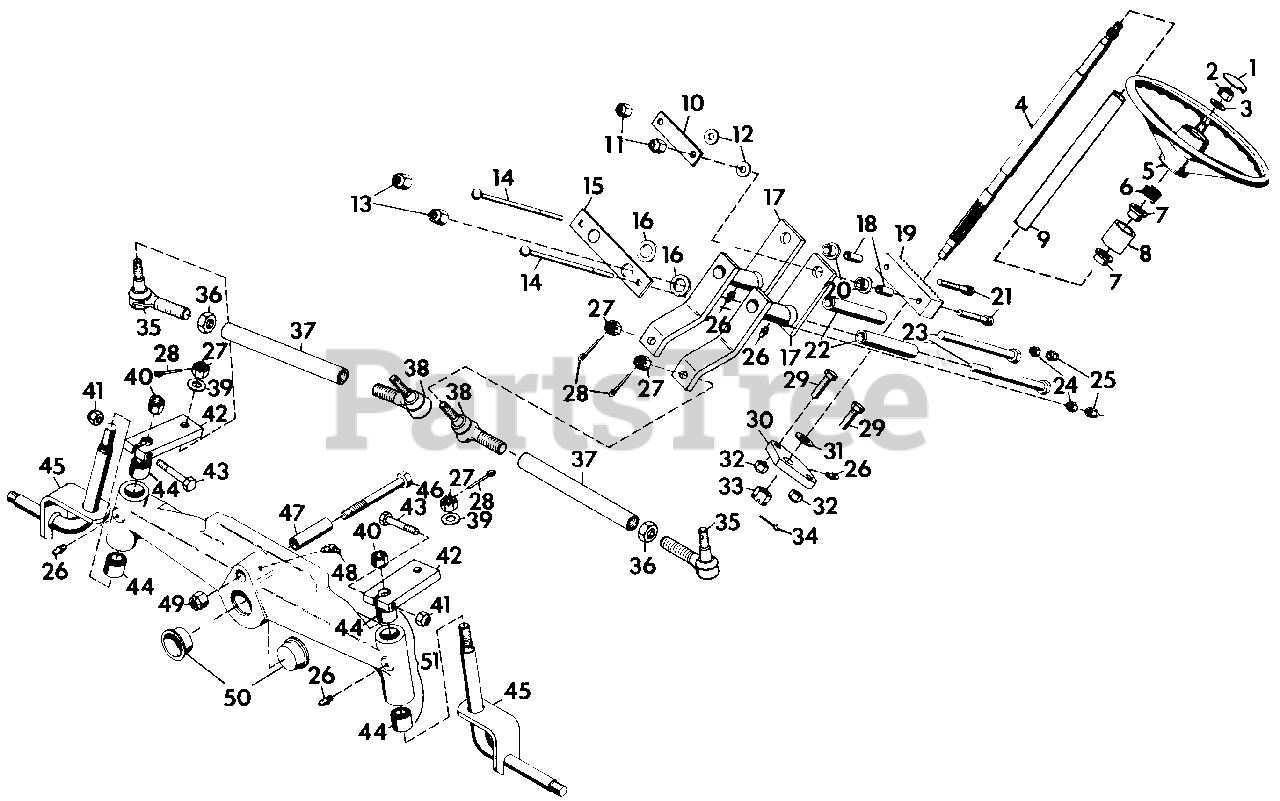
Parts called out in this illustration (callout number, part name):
1	CAP, STEERING WHEEL
2	NUT, JAM 5/8-11 HEX
3	WASHER, FLAT .656X1.312X.095
4	SHAFT, STEERING WHEEL
5	WHEEL, STEERING
6	SPRING, COMP. 1.00X.80X36 LB/IN
7	BUSHING, NYLON .760X1.000X.600 FLANGE
8	BUSHING, STEERING WHEEL
9	TUBE, PLASTIC 1.0 I.D.
10	STRAP, RACK AND PINION
11	NUT, LOCK 3/8-16
12	WASHER, FLAT .375X1.125X.065
13	NUT, LOCK 1/2-13
14	BOLT, 5/16-18X5.5 RD HD SQ NK
15	PLATE, ADJUSTMENT
16	RACE, BEARING THRUST .752X1.240X.095
17	WELDMENT, STEERING
18	BUSHING, .391X.622X.670
19	GEAR, RACK
20	BEARING, FLANGE(P/M BRONZE)
21	SCREW, CAP 3/8-16X2.0 HEX SOCKET HD
22	SLEEVE, PIVOT
23	BOLT, HEX 1/2-13X6.0
24	NUT, HEX 5/16-18
25	NUT, LOCK 5/16-18
26	FITTING, LUBE 1/4-28
27	NUT, HEX SLOTTED 3/8-24
28	PIN, COTTER .09X.75
29	BOLT, HEX 7/16-14X1.5
30	SUPPORT, STEERING SHAFT
31	RACE, THRUST
32	NUT, LOCK 7/16-14
33	NUT, HEX 1/2-13 SLOTTED
34	PIN, COTTER .09X1.00
35	ASSEMBLY, ROD END
36	NUT, JAM 1/2-20
37	TUBE, TIE ROD
38	ASSEMBLY, ROD END
39	WASHER, FLAT .438X1.000X.083
40	NUT, HEX 5/8-11
41	NUT, LOCK 5/16-24
42	ARM, TIE ROD AXLE
43	BOLT, HEX 5/16-24X1.75
44	BUSHING, .877X1.004X1.0
45	WELDMENT, KING PIN
46	BOLT, HEX 3/4-10X4.5
47	TUBE, AXLE PIVOT
48	FITTING, LUBE 45 DEG.
49	NUT, LOCK 3/4-10
50	CAP, FRONT AXLE
51	AXLE
